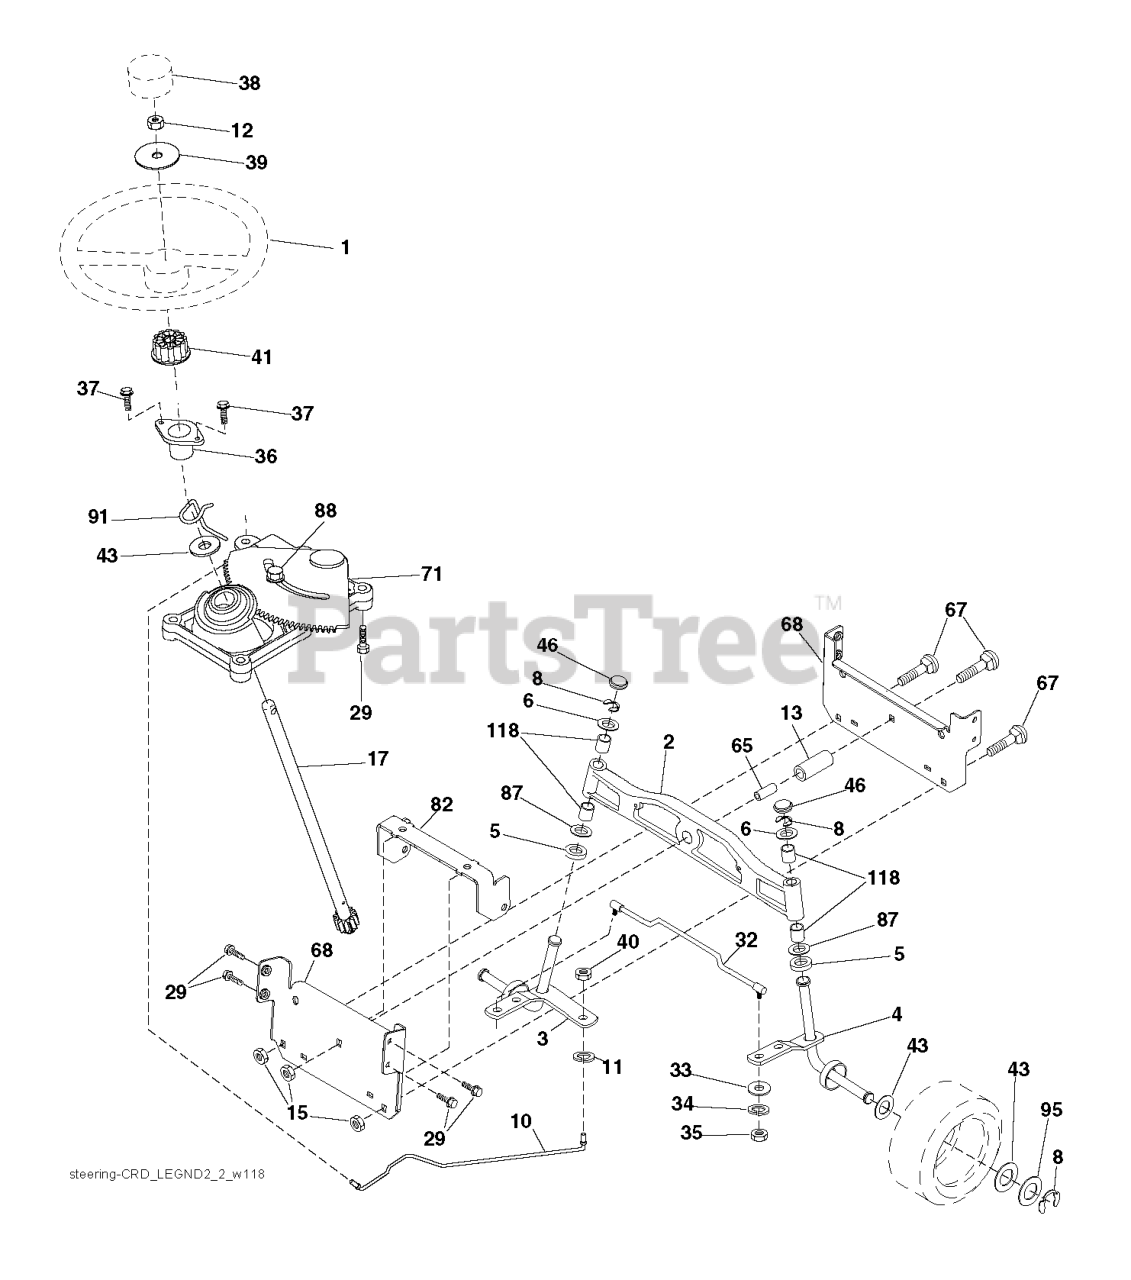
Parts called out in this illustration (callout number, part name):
1	RP WHEEL.STEER.HUSQ.PREM.OVMLD
2	AXLE.ASM.LT.CAST.LGHTWGHT
3	SPINDLE.ASM.LH.15"TIRES
4	SPINDLE.ASM.RH.15"TIRES
5	THRUST WASHER
10	DRAGLINK.15".TIRES.2001
11	WASHER, LOCK 3/8
12	NUT.HEX.1/2-20
13	TUBE, PIVOT AXLE
15	NUT
17	SHAFT ASM STRG
29	SCREW, 3/8-16X3/4
33	WASHER M
34	WASHER.LOCK.HVY.HLCL.SPR.5/16
35	NUT, CROWNLOCK
36	BUSHING, STRG. BLK
37	SCREW.TT.#10-32X.5.3/8.FLANGE
38	RP INSERT.CAP.WHL.STRG.HUSQ.
39	WASHER 9/16"ID, 2 3/8"OD
40	NUT CROWNLOCK 3/8-24
41	ADAPTER, WHEEL STNG..
46	CAP.SPINDLE.BLACK
65	SPACER.BRACE.AXLE
67	BOLT CARRIAGE
68	BRACE.AXLE.15"TIRES
71	STEERING ASM
82	BRACKET.SUSP.CHASSIS.FRONT.15
87	WASHER, FLAT .781 X 1 1/2"
88	BOLT, SHOULDER 7/16-20
91	CLIP.STEERING
95	WASHER.HARDENED
118	BUSHING, AXLE CAST
